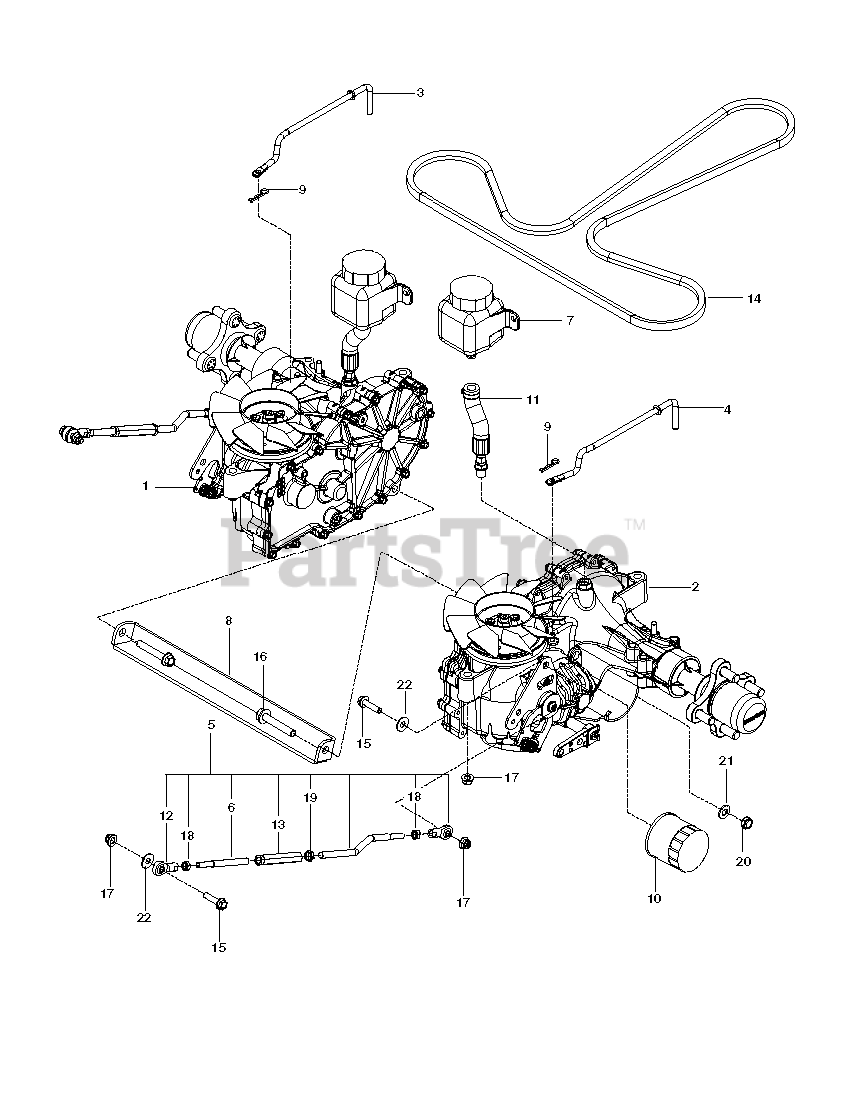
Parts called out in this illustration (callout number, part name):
1	HG_TRANS, ZT-3400, RT
2	HG_TRANS, ZT-3400, LT
3	LINKAGE, RIGHT BYPASS
4	LINKAGE, LEFT BYPASS
5	ASSEMBLY, CONTROL LINKAGE
6	LINKAGE, CONTROL, FT
7	TANK.EXPANSION.350ML 71328
8	BRACKET CMBR XMSM BLK
9	HAIRPIN #2
10	HG_FILTER, ZT4800 52114
11	ASSEMBLY, HOSE, EXPANSION
12	BALL JOINT, RIGHT HANDED
13	TURNBUCKLE, 3/8
14	BELT, "AX", 86.7"
15	HHFS 5/16-18 X 1.25 TPBLT GD 5
16	HHFS 3/8-16 X 2.25 GD 8
17	NUTNYLOK.FLRANGE.5/16-18
19	NUT 3/8-24 JAM
20	LOCK NUT 3/8-15 GR C Z/Y
21	WASHER 3/8 SAE FLAT
22	WASHER 5/16 FLAT
